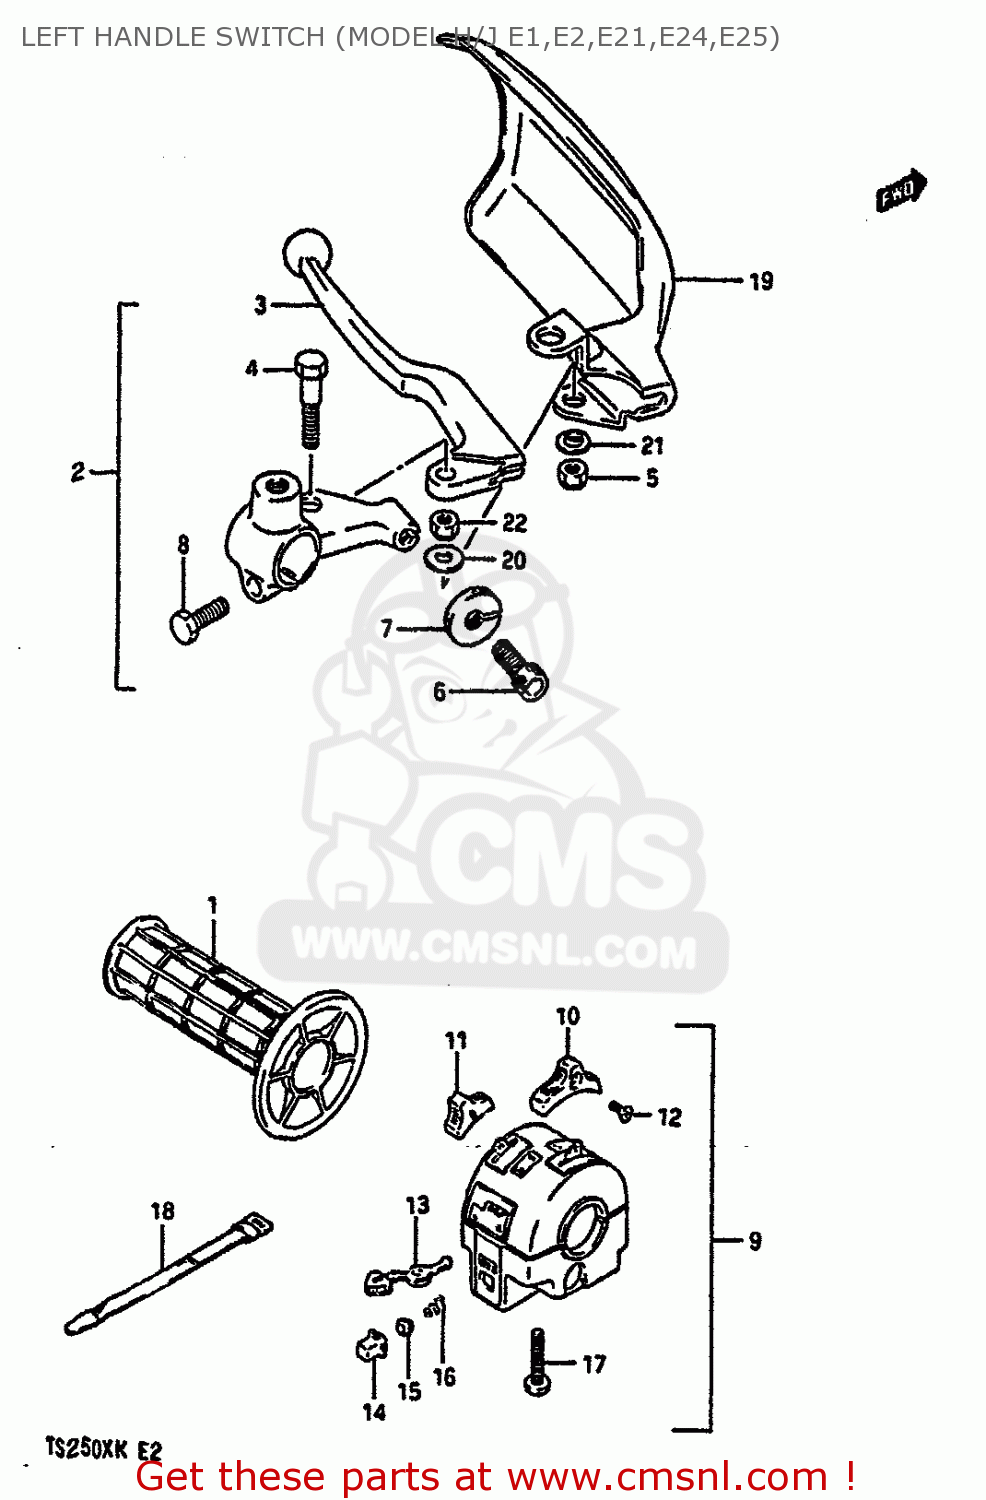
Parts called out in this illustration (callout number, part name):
1	GRIP,LEFT
2	LEVER ASSY,CLUTCH
3	LEVER,CLUTCH
4	BOLT,LEVER SET
5	NUT
6	ADJUSTER,CABLE
7	NUT,CABLE ADJUSTER LOCK
8	BOLT
9	SWITCH ASSY,HANDLE LH
10	KNOB,LIGHTING SWITCH
11	KNOB,DIMMER SWITCH
12	SCREW
13	KNOB,TURNSIGNAL
14	BUTTON,HORN
15	CONTACT
16	SPRING
17	SCREW
18	CLAMP(L:120)
19	COVER,KNUCKLE,L
20	WASHER(6.5X16X1.2)
21	WASHER
22	NUT 6MM
